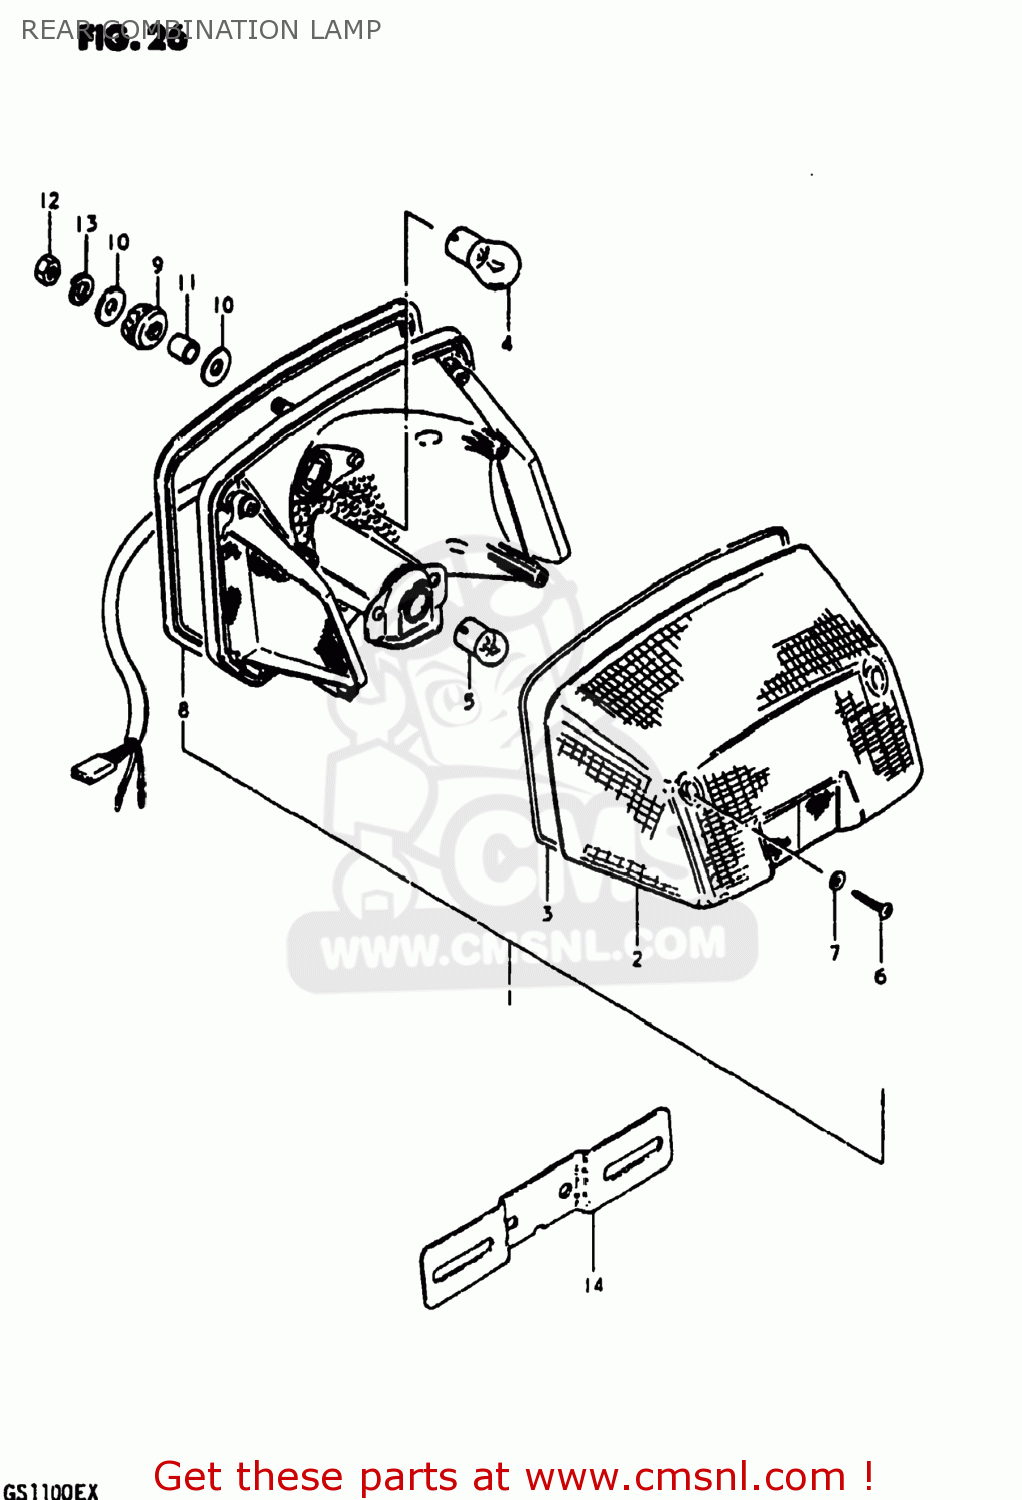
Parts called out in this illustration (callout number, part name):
1	LAMP ASSEMBLY,REAR COMBINATION
2	LENS
3	GASKET (NAS)
4	BULB(12V23W)
5	BULB
6	SCREW
7	GASKET (NAS)
8	GASKET,REAR COMBINATION LAMP
9	CUSHION
10	WASHER
11	SPACER (6.8X10X11.5)
12	NUT
13	LOCK WASHER
14	PLATE,REAR LICENSE
